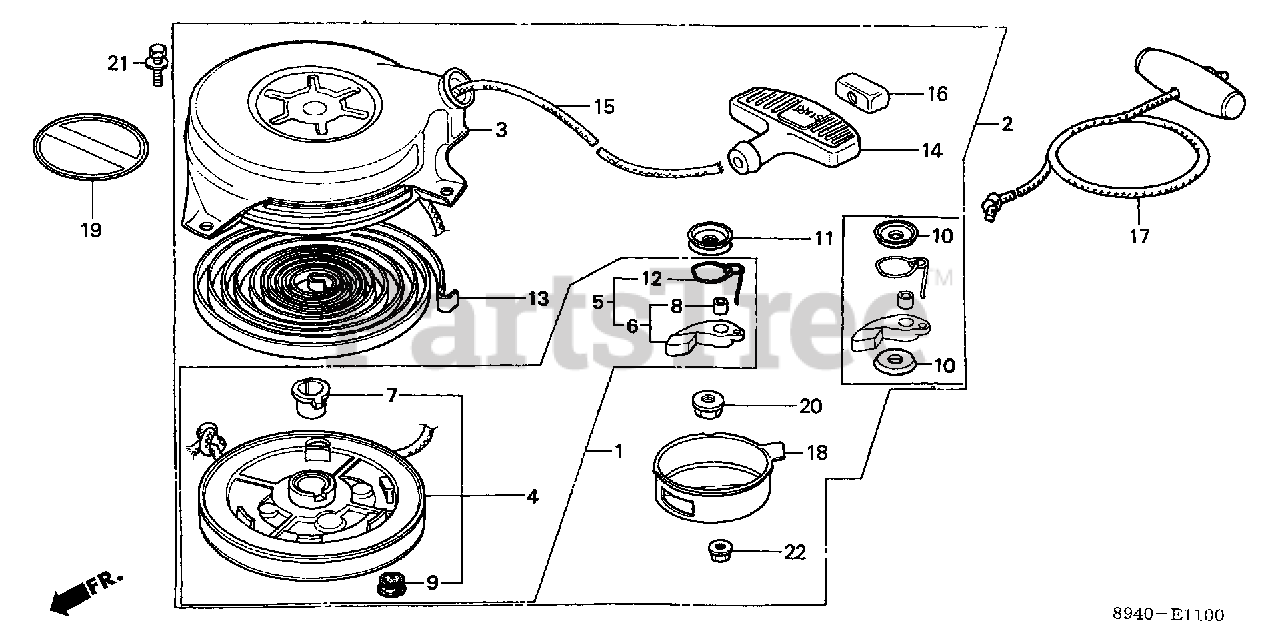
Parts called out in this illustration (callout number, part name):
1	REEL, STARTER
2	STARTER ASSY., RECOIL *NH67* (SPARKLE WHITE)
2	STARTER ASSY., RECOIL *R8* (BRIGHT RED)
2	STARTER ASSY., RECOIL *NH67* (SPARKLE WHITE) (NOT AVAILABLE)
3	CASE, STARTER *R8* (BRIGHT RED)
3	CASE, STARTER *NH67* (SPARKLE WHITE)
4	REEL, STARTER
5	RATCHET KIT
7	BOSS, REEL
8	BUSH, RATCHET
9	BUSH, REEL STARTER
10	PLATE, FRICTION
11	PLATE, FRICTION
12	SPRING, FRICTION
13	SPRING, RETURN
14	GRIP, STARTER
15	ROPE, RECOIL STARTER (#5X55")
15	ROPE, STARTER (#5X55") (NOT AVAILABLE)
16	SUPPORT, GRIP
17	ROPE, STARTER (#5X55")
18	COVER, REEL STARTER
19	EMBLEM (HP)
20	NUT, SELF-LOCK (8MM)
21	BOLT, FLANGE (6X8)
22	NUT, FLANGE (5MM)
